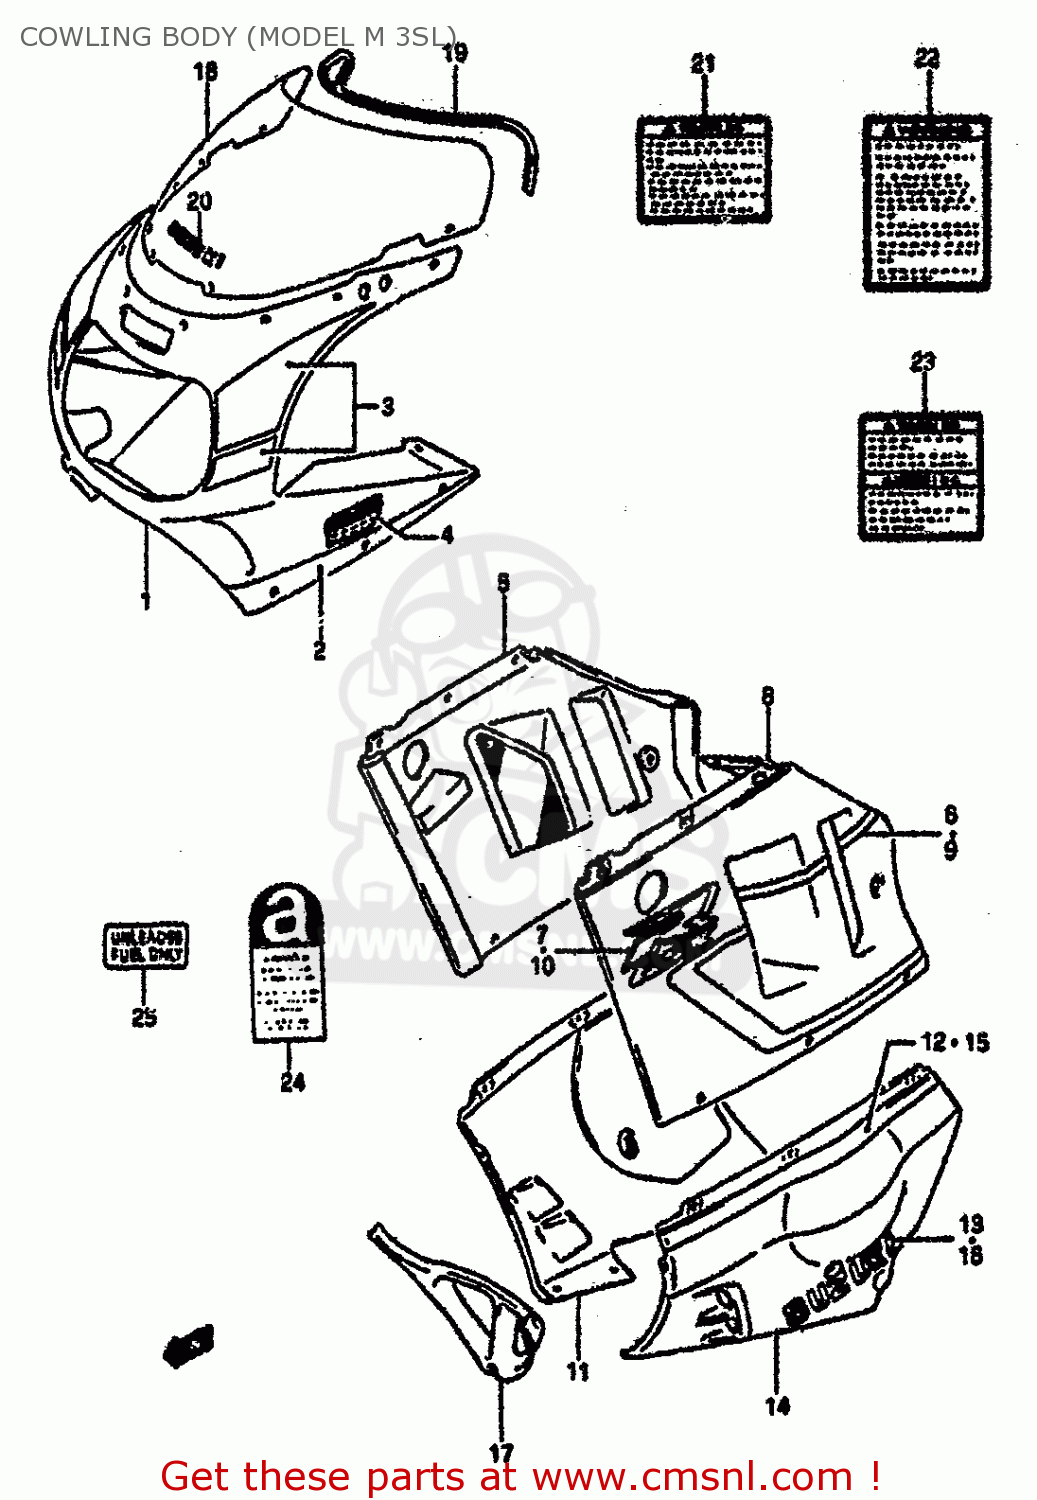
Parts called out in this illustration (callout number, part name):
1	BODY ASSY, COWLING (WHITE)
2	TAPE SET,COWLING
3	TAPE SET,COWLING,UPPER
4	EMBLEM,COWLING UNDER,SACS
5	COVER, COWL SIDE RH (BLUE/BLUE)
6	TAPE SET,COWL SIDE STRIPE,R
7	EMBLEM,COWLING SIDE
8	COVER, COWL SIDE LH (BLUE/BLUE)
9	TAPE SET,COWL SIDE STRIPE,L
10	EMBLEM,COWLING SIDE
11	COWLING COMP,UNDER,RIGHT
12	TAPE,COWLING,UNDER STRIPE
13	EMBLEM,SUZUKI
14	COWLING,UNDER,L
15	TAPE,COWLING,UNDER STRIPE
16	EMBLEM,SUZUKI
17	COWLING,UNDER CTR
18	SCREEN SET,WIND
19	MOLDING
20	EMBLEM,SUZUKI(WHITE)
21	LABEL, WARNING SAFETY
22	LABEL (WARNING SCREEN)
23	LABEL (WARNING)
24	LABEL,ASBESTOS WARNING
25	LABEL,FUEL CAUTION
